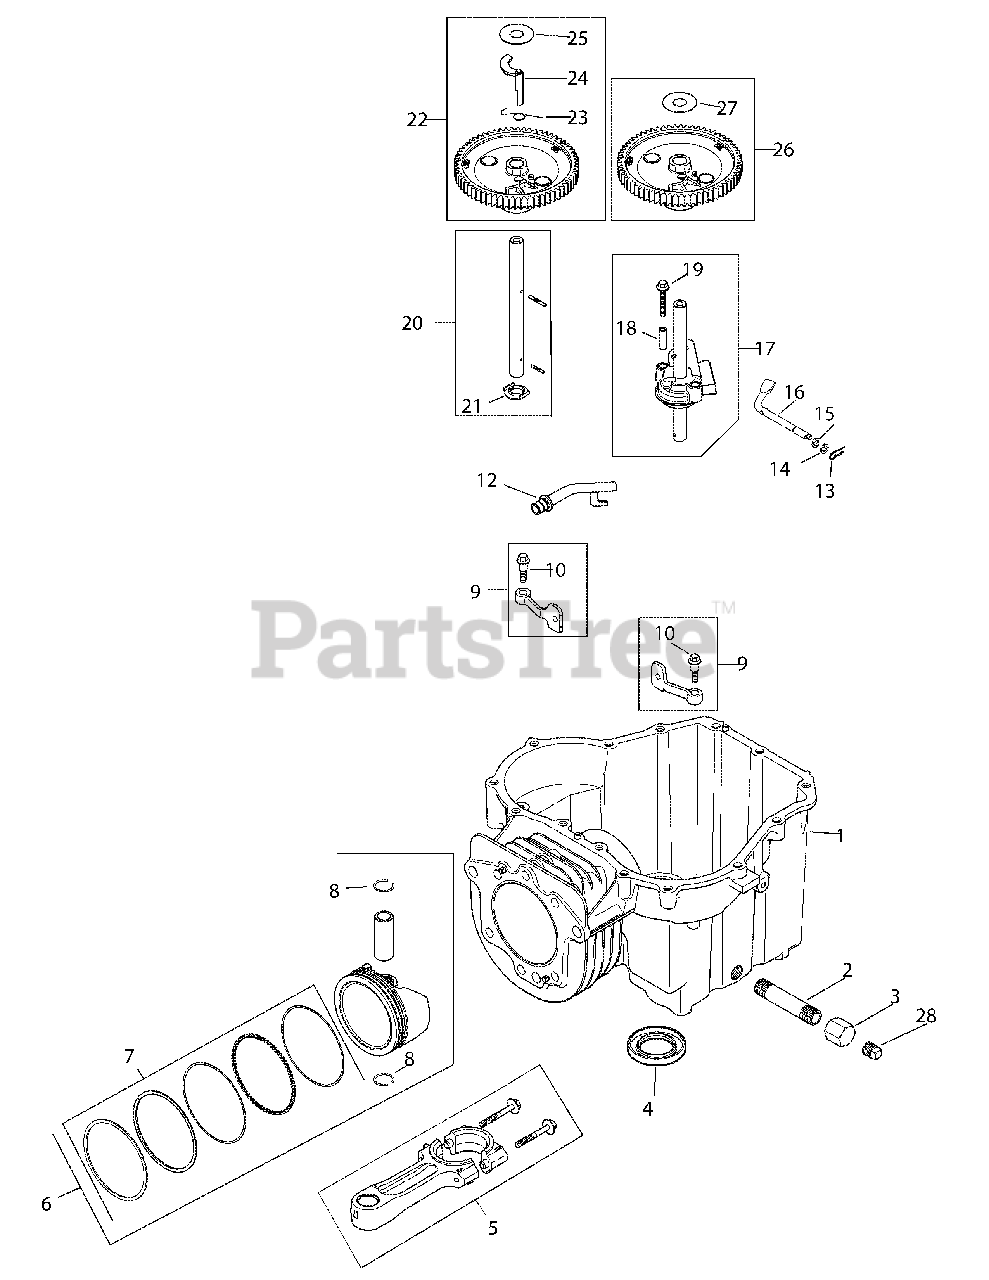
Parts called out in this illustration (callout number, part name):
1	Crankcase
4	Oil Seal
5	Connecting Assembly Rod
6	Piston w/ Ring Set, 94mm (Incl. 7, 8)
7	Ring Set (94mm)
8	Piston Pin Retainer
9	Cam Lever Ass. Kit (Incl. 10)
10	Shd. Thd. Frm. Screw, M6 X 1 X 26
12	Drainback Tube
13	Hitch Pin Clip
14	Flat Washer, 6 Mm
15	Flat Washer, 1/4
16	Governor Cross Shaft
17	Oil Pump Ass’y Kit (Incl. 11, 18, 19)
18	Oil Pump Screw Spacer
19	Oil Pump Screw
20	Cam Center Shaft Kit (Incl. 21)
21	Thrust Washer
22	Camshaft Ass’y Kit (Incl. 23-25)
24	Acr. Weight
25	Thrust -Acr. Washer
26	Camshaft Ass’y Kit (Incl. 27)
27	Thrust -Acr. Washer
28	Square Head Pipe Plug, 3/8
